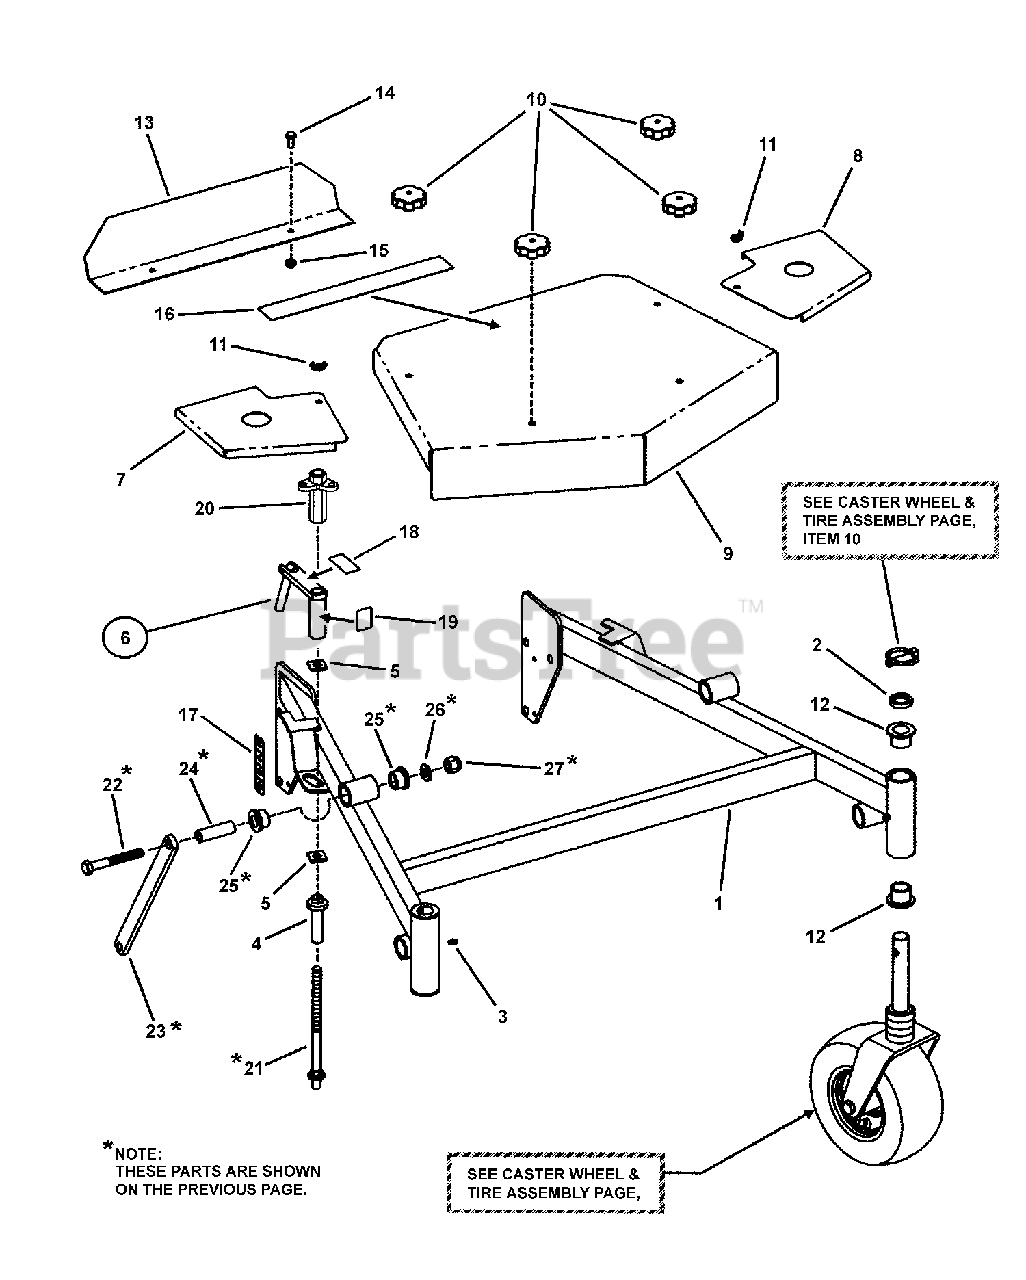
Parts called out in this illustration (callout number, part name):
1	WELDMENT, 48" Deck Frame
1	WELDMENT, 52" Deck Frame
1	WELDMENT, 61" Deck Frame
2	SPACER, Powdered Metal
3	FITTING, 1/4-28 Straight Lube
4	LIFT WASHER (Weldment)
5	WASHER, Lift
6	ASSEMBLY, Crank
7	COVER, 48" Right
7	COVER, 52" Right
7	COVER, 61" Right
8	COVER, 48" Left
8	COVER, 52" Left
8	COVER, 61" Left
9	COVER, 48" Center
9	COVER, 52" Center
9	COVER, 61" Center
10	KNOB, Hood (5/16-18 thread)
11	WING NUT, 5/16-18
12	BUSHING
13	SHIELD, Muffler (SPA610, SPA611)
14	BOLT, 5/16-18 X 3/4 GD5
15	NUT, 5/16-18 HEX NYLON LOCK
16	DECAL, SNAPPER Pro w/Trademark
17	DECAL, Height of Cut
18	DECAL, Caution Handle May Be Hot (Adjustable Decks only)
19	DECAL, Oil Threads Here (Adjustable Decks only)
20	WELDMENT, Pro Knob
21	STUD, Lift, 1/2-13 Thread, Both Ends
22	BOLT, 1/2-13 x 3-3/4" Hex Head, GR 5
23	ARM, Suspension, 12" Long
23	ARM, Suspension, 13-1/2" Long
24	BUSHING, Suspension
25	BUSHING, Suspension
26	WASHER, 1/2" Flat
27	NUT, 1/2-13 Hex Nyloc
